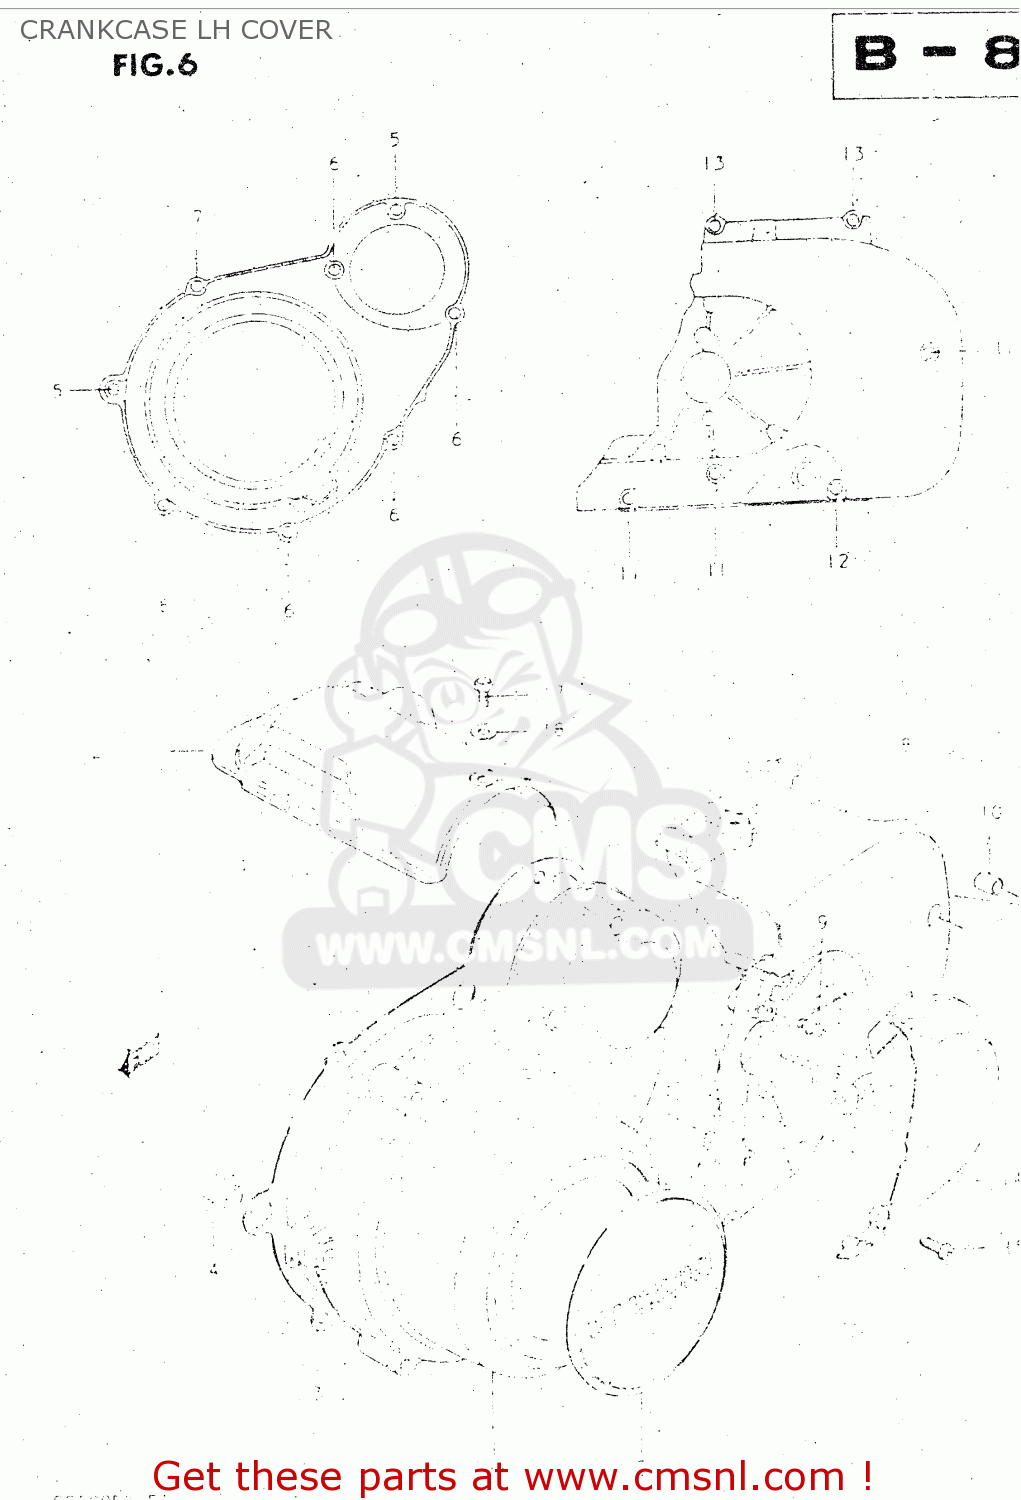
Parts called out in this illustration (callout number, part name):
1	COVER
2	EMBLEM,MAGNETO COVER
3	GASKET,MAGNETO COVER (MCA)
4	PIN
5	SCREW (6X45)
6	SCREW
7	SCREW (6X35)
8	CRANKCASE SET
9	NIPPLE
10	PIN
11	SCREW
12	SCREW 6X80
13	SCREW 6X30
14	CAP,CLUTCH RELEASE ADJUST
15	SCREW
16	COVER,STARTER MOTOR
17	BOLT
18	WASHER
